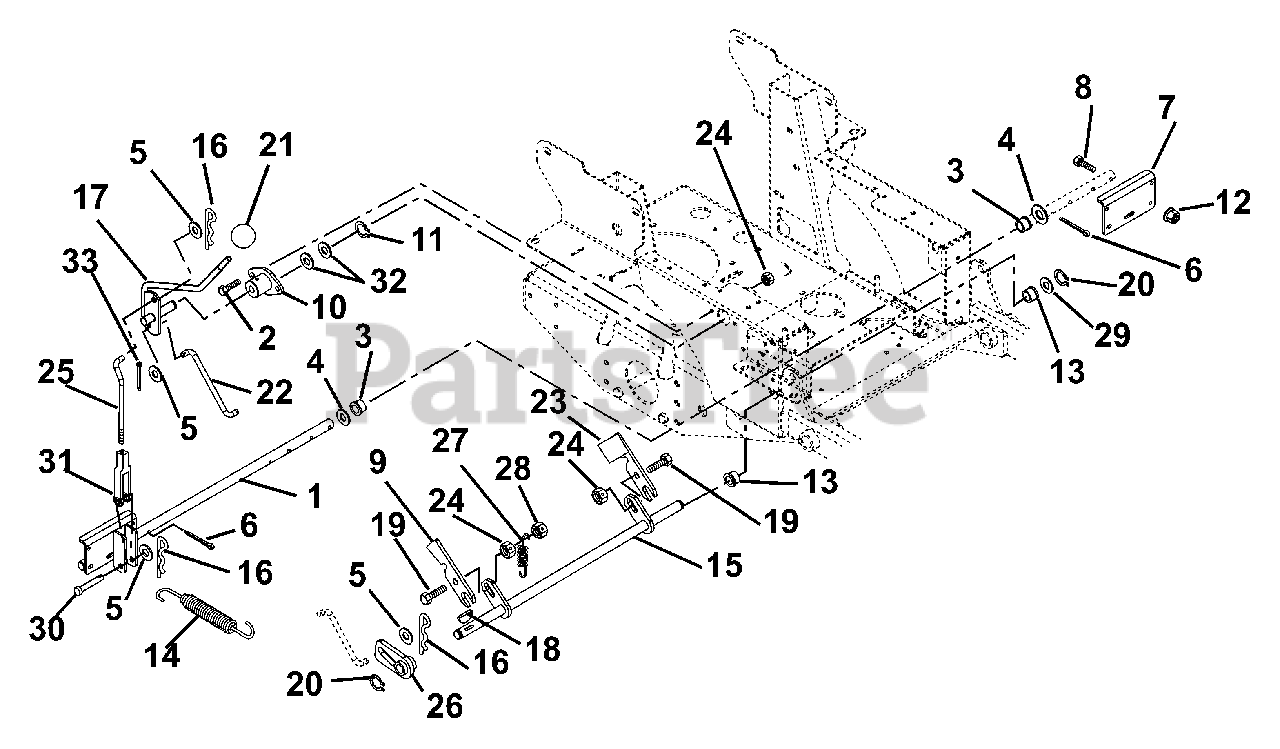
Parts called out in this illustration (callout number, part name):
1	Weldment, Brake Shaft
2	Bolt, Hex .31-18 x 1.00 Grade 5
3	Bushing, Flange .762 x 1.00 x .58 x 1.48 Nylon
4	Washer, Flat Steel .755 x 1.375 x .062
5	Washer, Flat Steel .406 x .812 x .065
6	Pin, Cotter .12 x 1.00 Extended Prong Square Cut
7	Paddle, Brake
8	Bolt, Hex .25-20 x 1.25 Grade 5
9	Slide, Interlocking Brake
10	Bushing, Flange
11	Ring, Retaining External .625 x .05
12	Nut, Nyloc Flange .25-20
13	Bushing, Flange .50 x .75 x .75 x 1.00
14	Spring, Engine Transmission
15	Weldment, Mechanical Brake
16	Pin, Hair
17	Weldment, Brake Actuating
18	Key, Woodruff .13 x .63
19	Bolt, Round Head Square Neck .31-18 x 1.25 Grade 5
20	Ring, Retaining External .50 x .05
21	Knob, Steering Lock
22	Linkage, Brake Actuating
23	Interlock, Safety Switch
24	Nut, Nyloc Flange 5/16-18
25	Linkage, Brake Compact-Z
26	Weldment, Parking Brake Hub
27	Spring, Tension .061 x .50 x 3.0
28	Nut, Locking Center .31-18
29	Washer, Flat Steel .505 x 1.00 x .062
30	Pin, Clevis .37 x 1.75
31	Clevis,.38-24 Adjustable
32	Washer-Flat-Steel .630 x 1.250 x .062
33	Pin, Cotter .09 x .75 Extended Prong Square Cut
